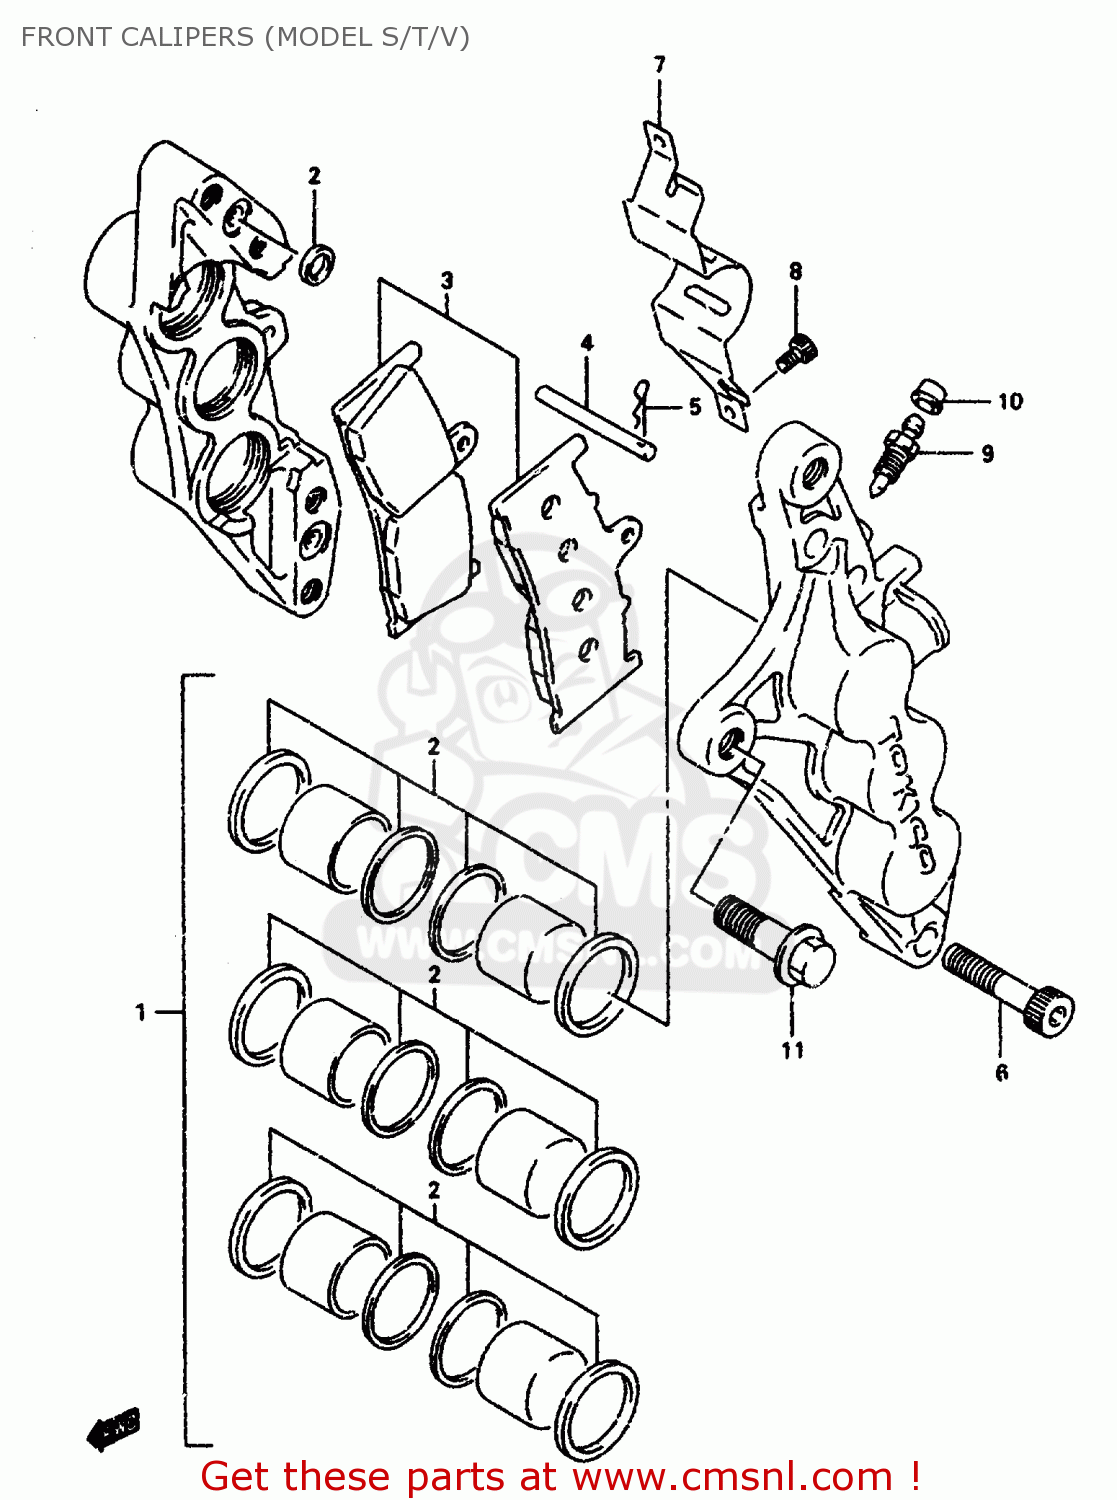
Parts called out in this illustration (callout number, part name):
1	PISTON SET
2	SEAL SET,PISTON
3	PAD SET (NAS)
4	PIN,PAD
5	CLIP,PAD PIN
6	BOLT,CALIPER
7	COVER,CALIPER
8	SCREW
9	BLEEDER
10	CAP,BLEEDER PLUG
11	BOLT
